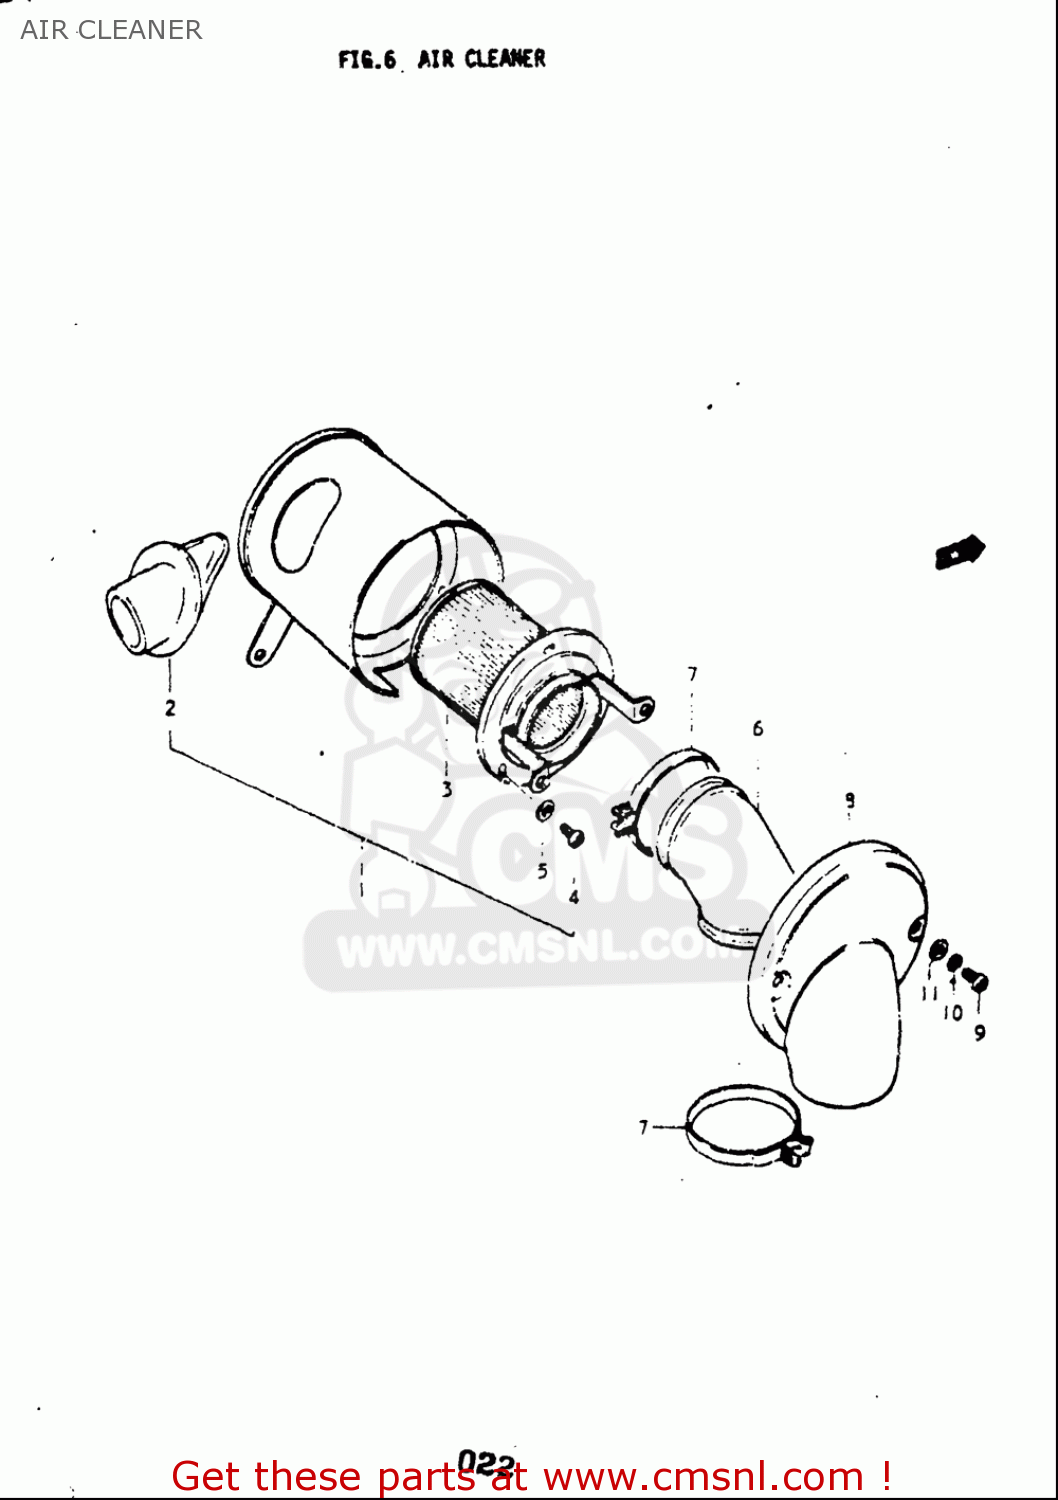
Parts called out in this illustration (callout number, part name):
2	PIPE,AIR CLEANER INLET
3	FILTER ASSY
4	SCREW
5	WASHER
6	HOSE,CARBURETOR AIR INLET
7	CLAMP
8	CAP,AIR CLEANER,R
9	SCREW
10	WASHER,LOCK
11	WASHER
